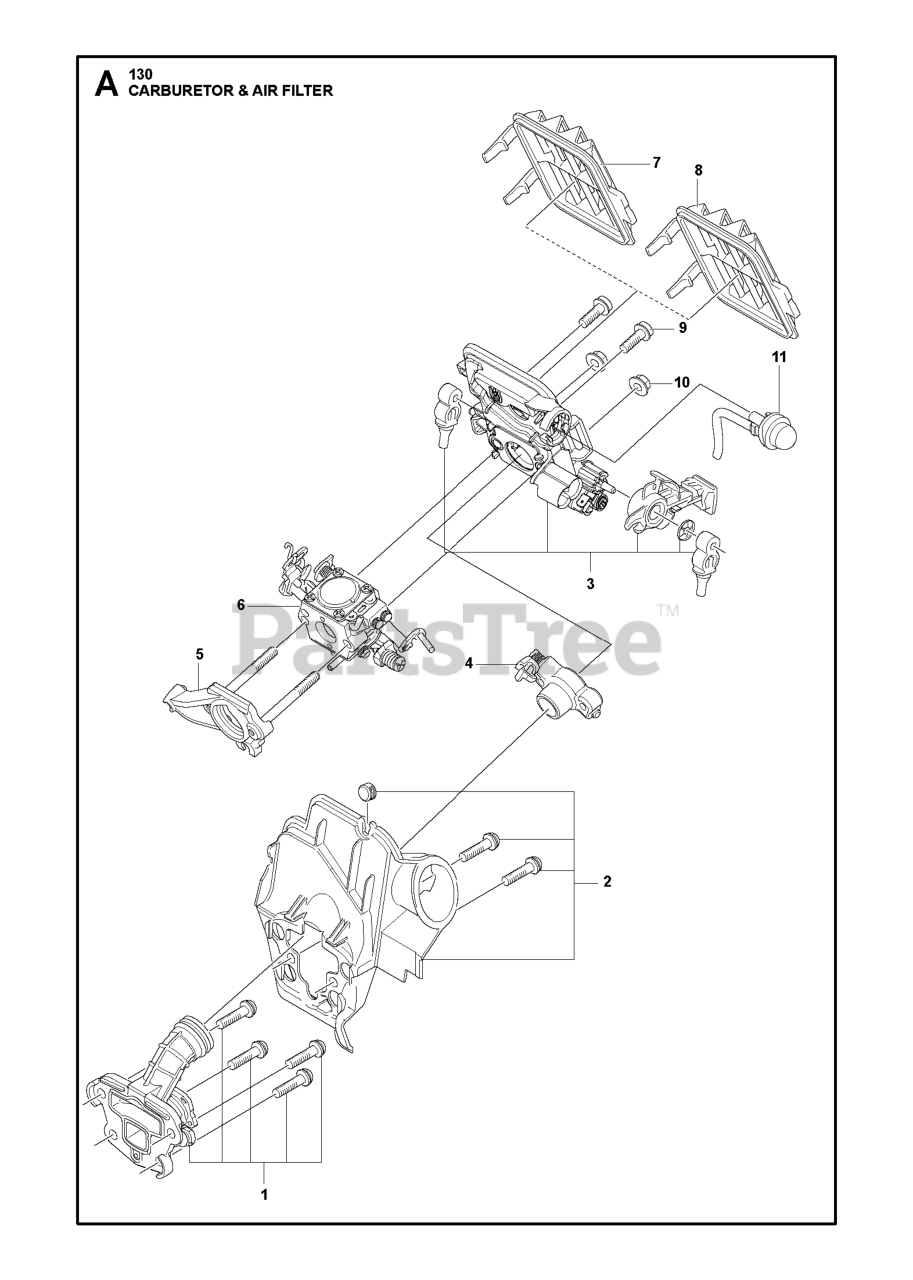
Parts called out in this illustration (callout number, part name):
1	INLET INTAKE BOOT
2	SERVICE KIT INSULATION WALL
3	SERVICE KIT FILTER HOLDER
4	VALVE ASSY AIR 130 CHAINSAW
5	FLANGE ASSY CARB H130 OVERMOLD
6	CARBURETOR
7	AIR FILTER MESH
8	AIR FILTER NON WOVEN
11	AIR PURGE BUBBLE
